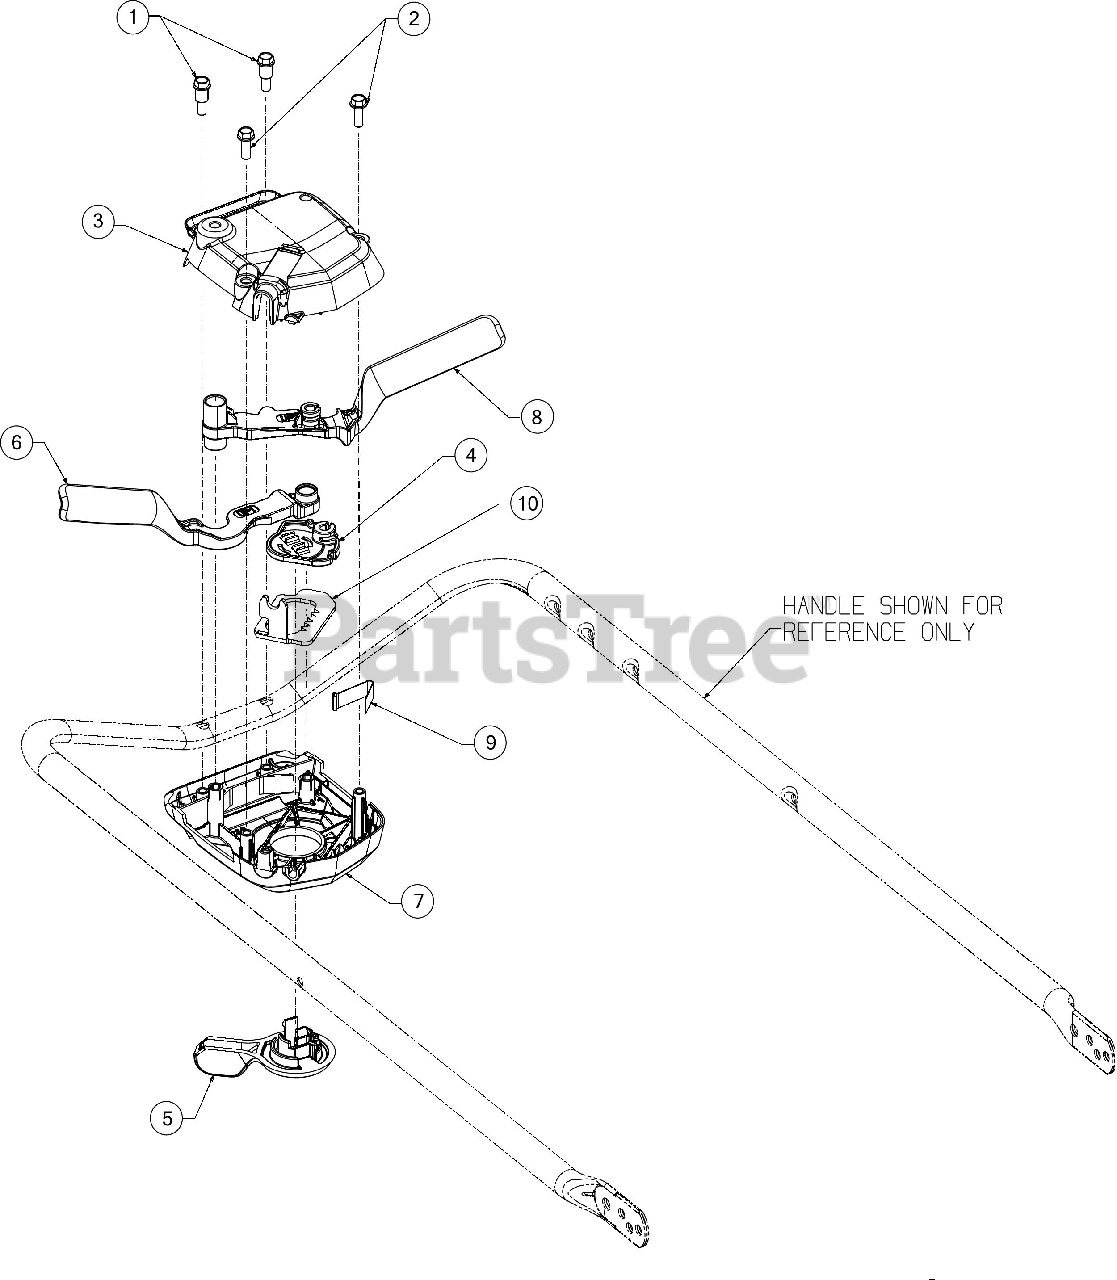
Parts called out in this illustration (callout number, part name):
1	SHOULDER SCREW 1/4-15 x .970
2	SCREW 1/4-15 x .750
3	LOWER CONTROL HOUSING
4	CABLE SPEED ADJUST ACTUATOR
5	SPEED SELECT LEVER
6	CONTROL LEVER (LH)
7	UPPER CONTROL HOUSING
8	CONTROL LEVER (RH)
9	SHIFT SPRING
10	RACK PLATE
